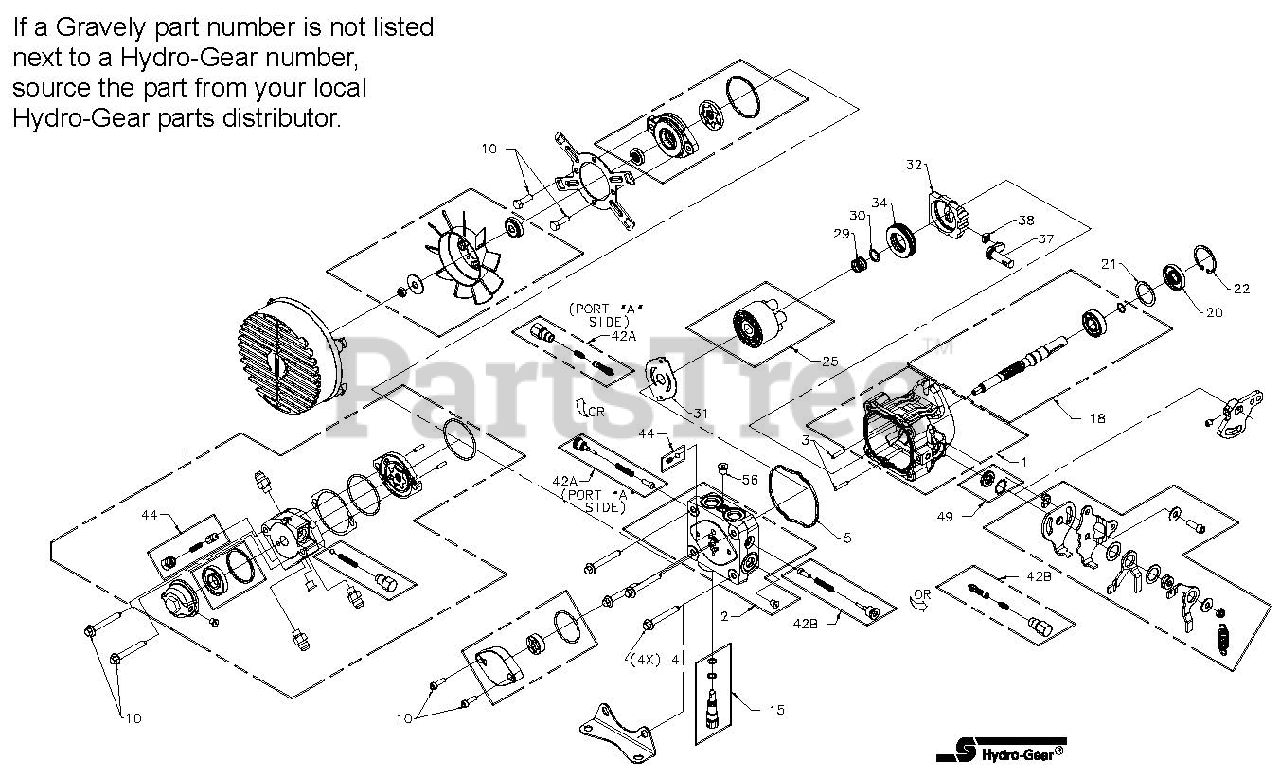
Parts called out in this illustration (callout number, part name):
1	Kit, Housing
2	Kit, End Cap W/PPT & STD
3	Pin, .219 x 1
4	Hex, Flange Bolt M8-1.25 x 60mm
5	Kit, Chg Pump
10	Screw, Cap M6 x 1 x 25
15	Kit, Bypass Valve
18	Kit, Pump Shaft 15mm Keyw
20	Seal, Lip 17 x 40 x 7
21	Washer 1.23 x 1.56 x .04
22	Ring, Ret 1.56 Int
25	Kit, 10 CC Block
29	Spring, Block
30	Washer, Thrust .59 x .78 x .04
31	Plate, Valve
32	Swashplate 10cc
34	Bearing, Thrust Ball 30 x 52 x 13
37	Arm, Trunnion 10 Cc
38	Guide, Slot
42	Kit, Shock Valve 200 Bar
44	Kit, Chg Relief
49	Kit, BDP-10l Seal
56	Plug 7/16-20 (Metal)
NS	Kit, Overhaul Seal
